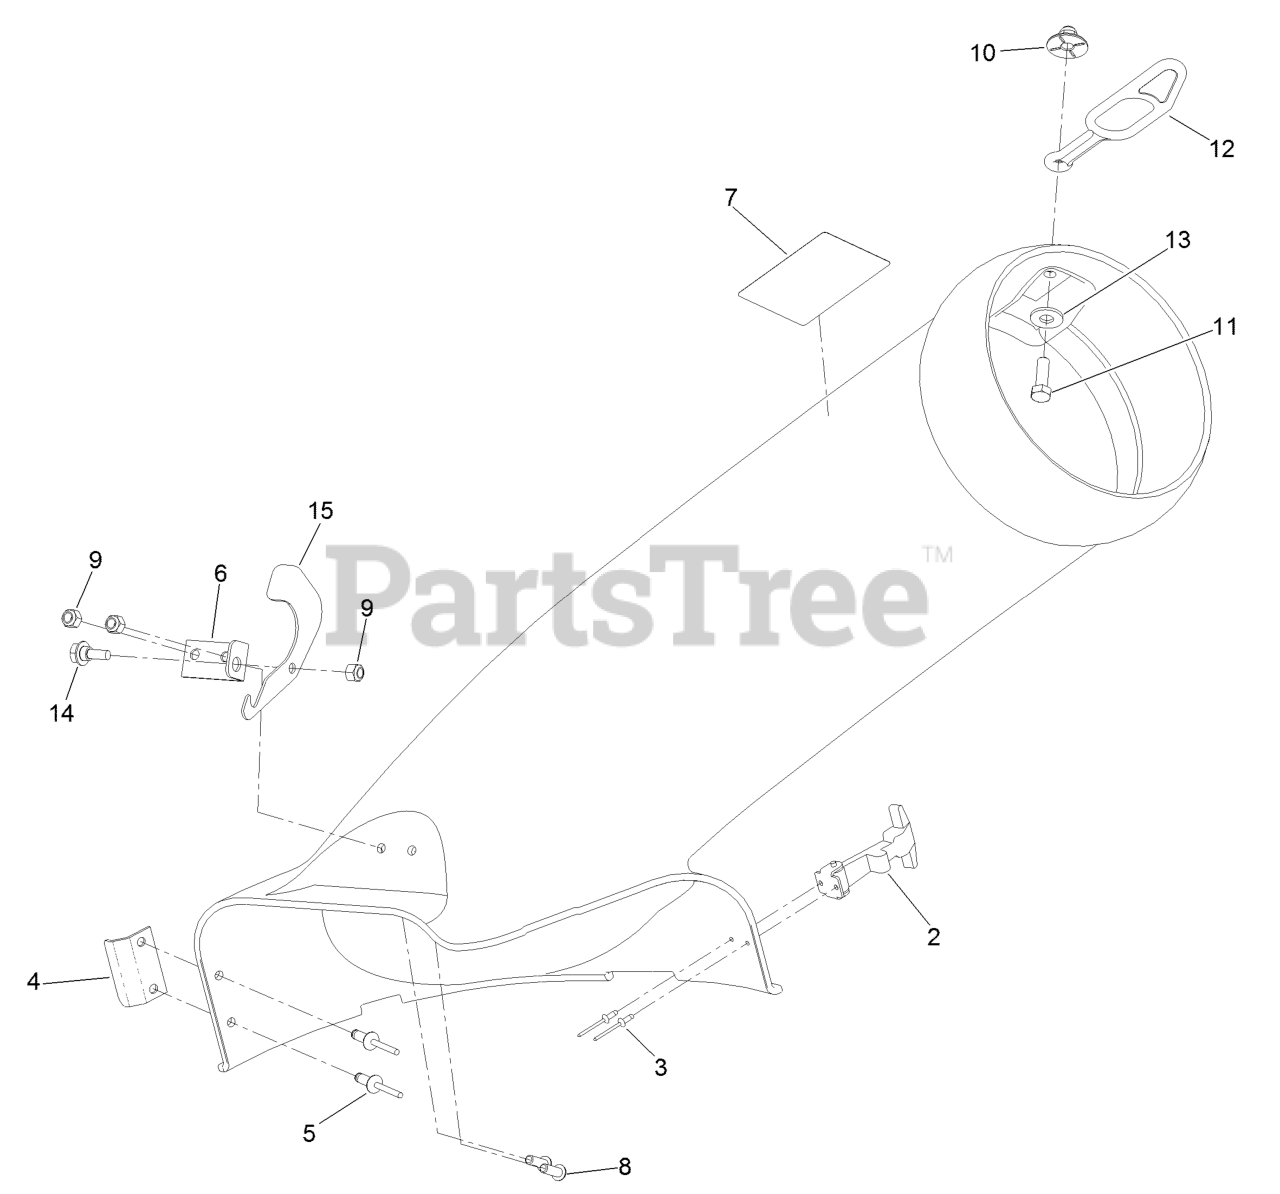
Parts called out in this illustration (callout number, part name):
2	HANDLE ASM
3	RIVET-POP
4	BRACKET-ELBOW
5	RIVET-BLIND
6	PLATE-PIVOT
7	DECAL-DANGER
8	SCREW-HSBH
9	NUT-LOCK, NI
10	NUT-IMPELLER
11	SCREW-HH
12	RETAINER-DUCT
13	WASHER-FLAT
14	SCREW-SHOULDER,HWH
